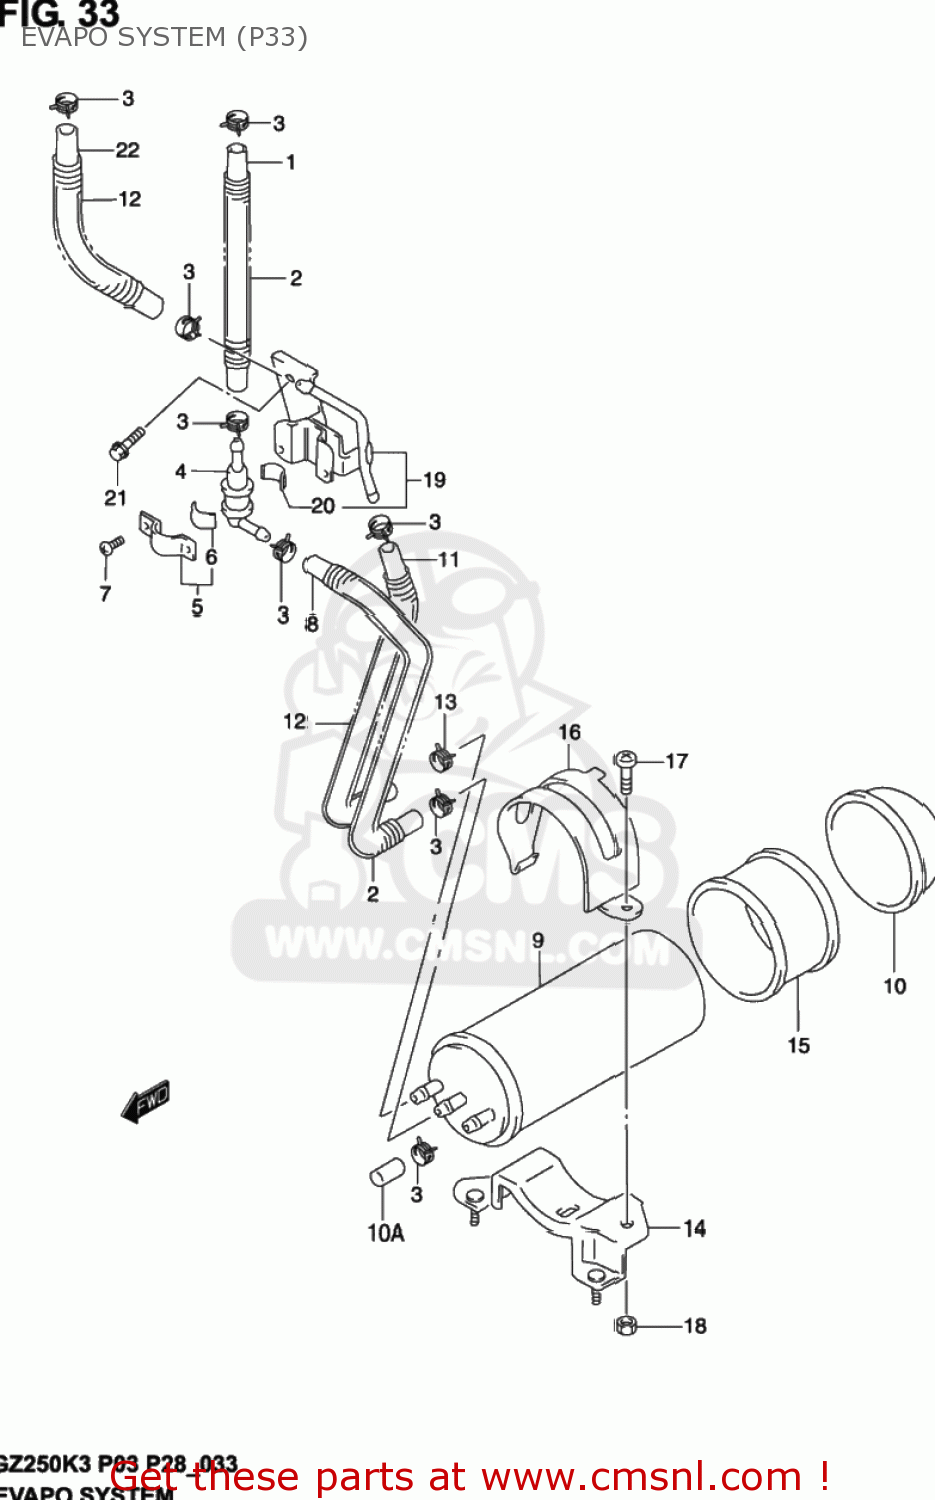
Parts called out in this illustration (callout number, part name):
1	HOSE(5.4X11.4X600)
2	SPRING
3	CLIP
4	VALVE,FUEL TANK BREATHER
5	PLATE,FUEL TANK BREATHER NO.2
6	CUSHION
7	SCREW
8	HOSE,BREATHER VALVE & CANISTER
9	CANISTER ASSY,CHARCOAL
10	CAP,CANISTER
10A	CAP,OD:11.5
11	HOSE,CSTR & CARB NO.1
12	SPRING
13	CLIP
14	BRACKET,CANISTER
15	CUSHION,CANISTER
16	HOLDER,CANISTER
17	SCREW 6X12
18	NUT
19	BRACKET,FUEL TANK BREATHER
20	CUSHION
21	BOLT
22	HOSE(5.4X11.4X600)
